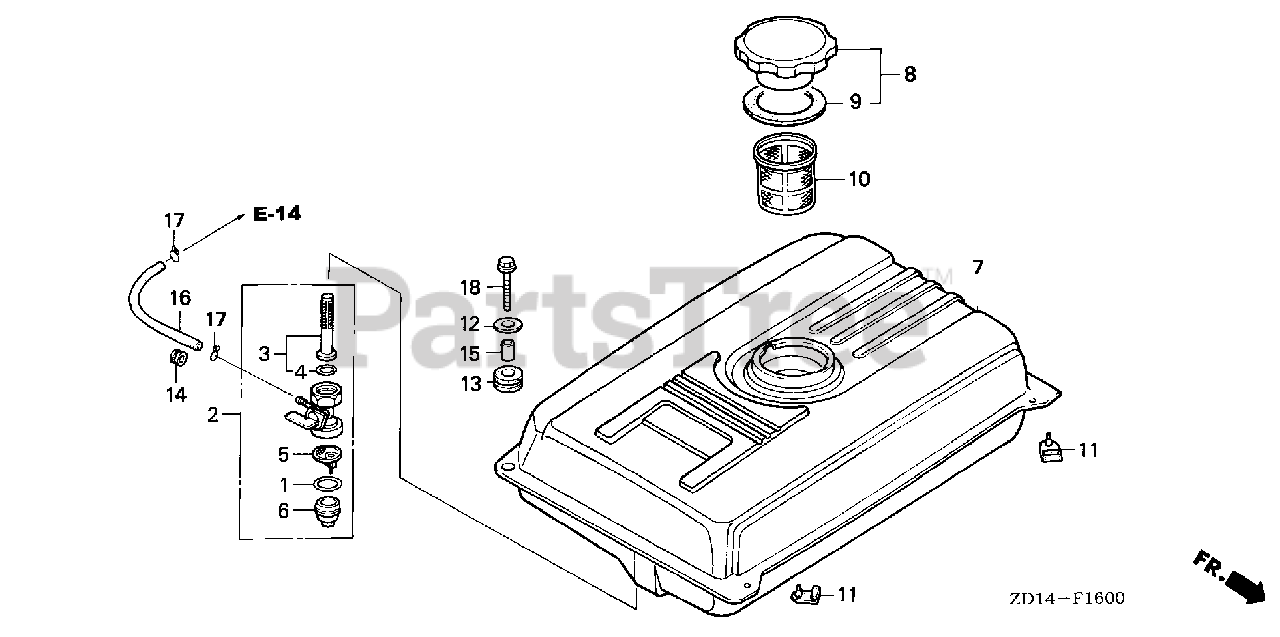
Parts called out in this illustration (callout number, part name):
1	GASKET, FUEL STRAINER CUP
2	PETCOCK ASSY.
3	SCREEN SET, FUEL STRAINER
4	O-RING (9.0X1.3)
5	FILTER, CUP
6	CUP, FUEL STRAINER
7	TANK, FUEL *R280* (POWER RED)
8	CAP, FUEL FILLER
9	GASKET, FUEL FILLER CAP
10	FILTER, FUEL
11	RUBBER, TANK MOUNTING
12	WASHER, TANK CUSHION
13	RUBBER, TANK CUSHION
14	RUBBER, FUEL (9X15X10)
14	RUBBER, FUEL (9X15X20)
15	COLLAR, TANK CUSHION
16	BULK HOSE, FUEL (4.5X3000) (4.5X150)
17	CLIP, TUBE (B8)
18	BOLT, FLANGE (6X22)
